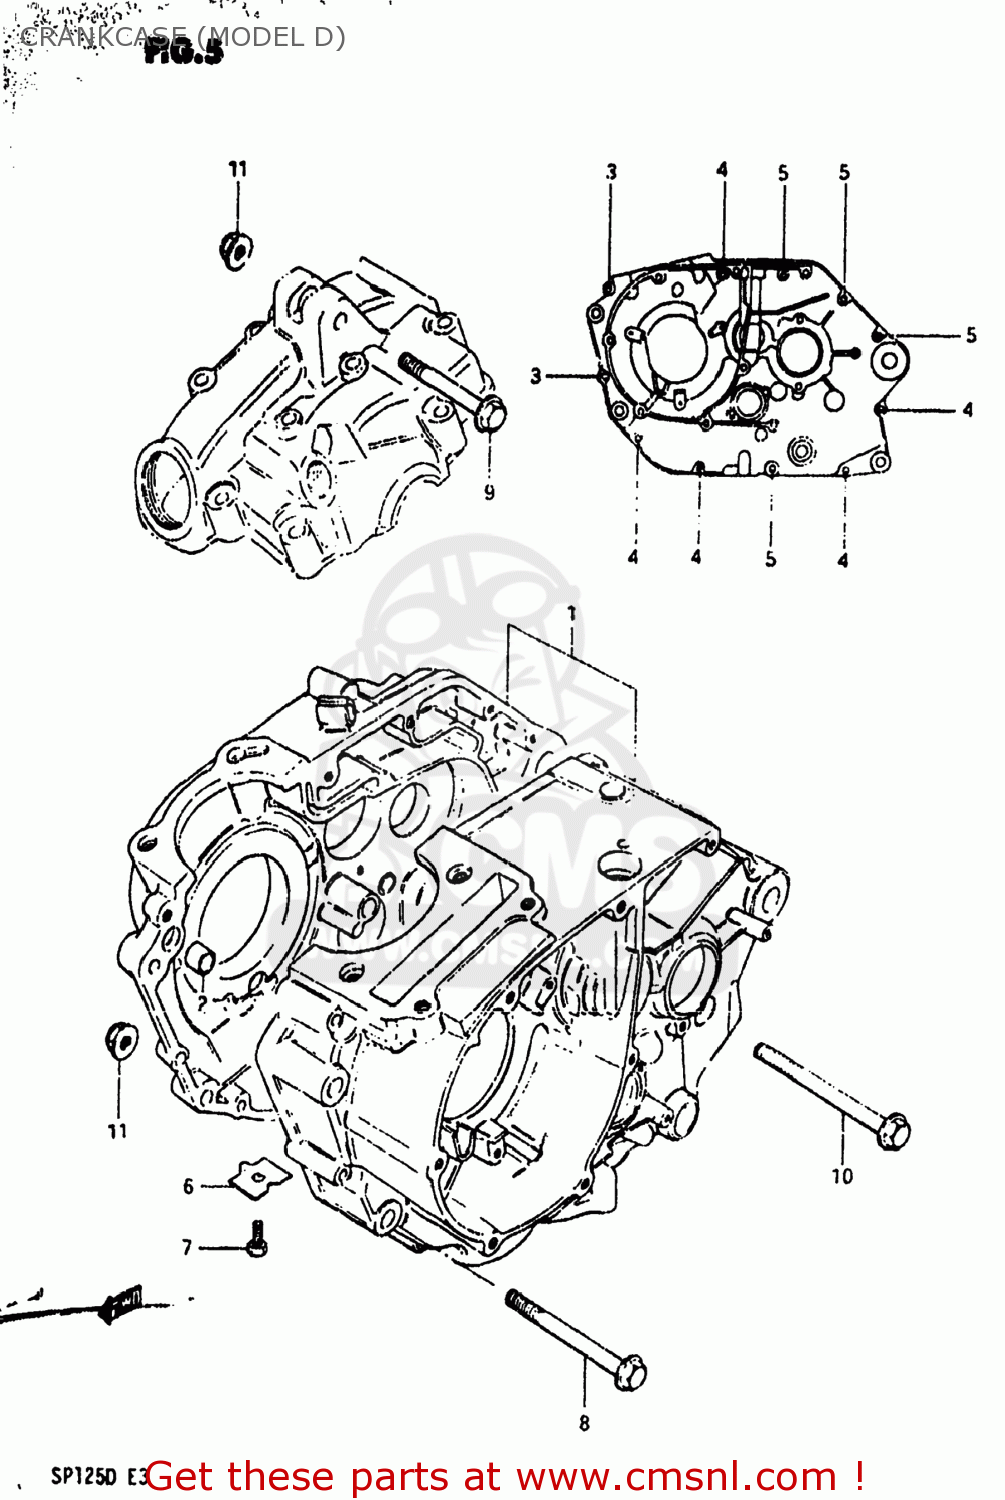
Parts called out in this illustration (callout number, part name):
1	CRANKCASE SET
2	PIN
3	BOLT (6X45)
4	BOLT (6X60)
5	BOLT (6X75)
6	PLATE,OIL GALLERY PLUG
7	BOLT
8	BOLT(8X80)
9	BOLT 8X50
10	BOLT 8X88
11	NUT
